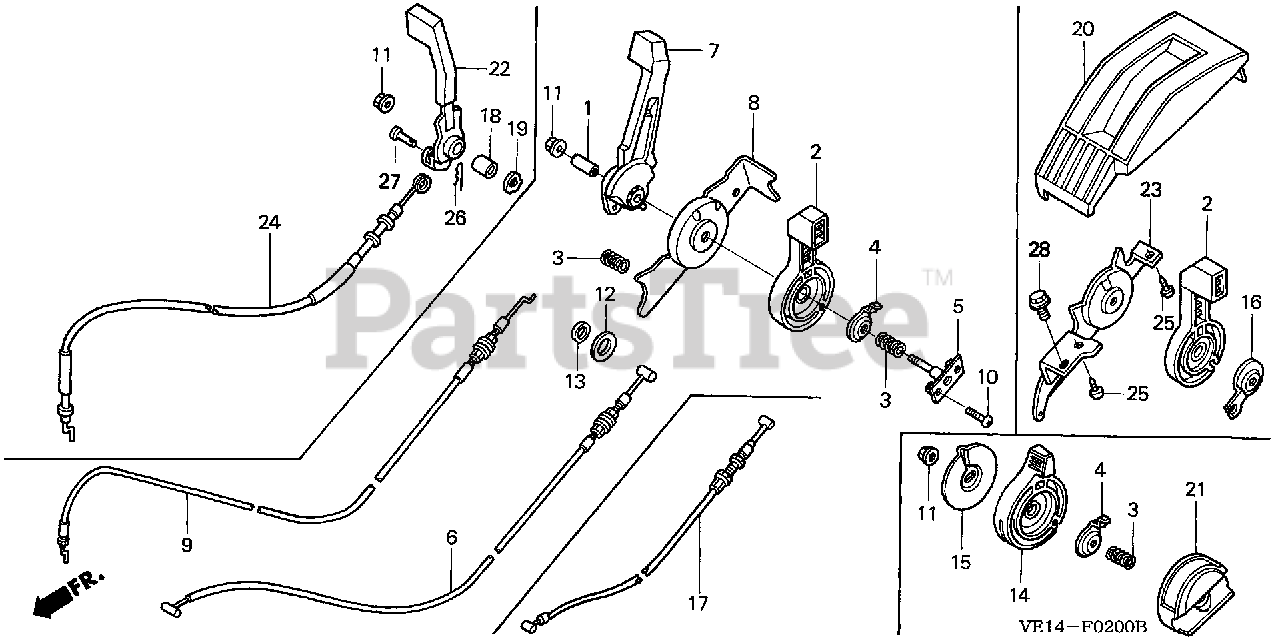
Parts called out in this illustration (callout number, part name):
1	COLLAR, AIR CLEANER
2	LEVER, THROTTLE
3	SPRING, THROTTLE LEVER
4	SEAT, SPRING
5	PIN, THROTTLE LEVER
6	CABLE, THROTTLE
7	LEVER, CHANGE
8	PLATE, STOPPER
9	CABLE, CHANGE
10	SCREW, PAN (6X32)
11	NUT, FLANGE (6MM)
12	WASHER, PLAIN (10MM)
13	WASHER, PLAIN (6MM)
